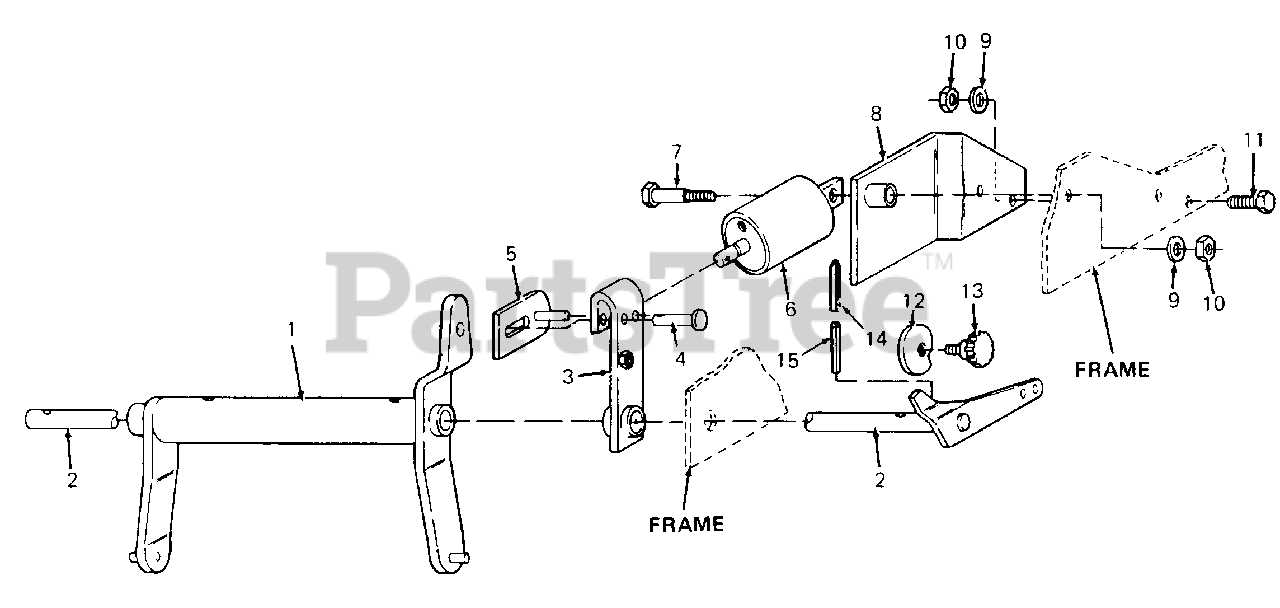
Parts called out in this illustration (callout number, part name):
1	Lift Assy, Rockshaft
2	Rockshaft Assy
3	Bracket, Lift
4	Pin, Clevis, 1/2 Dia X 2.172 Lg
5	Pin Assy, Lift
6	Cylinder, Hydraulic
7	Bolt, Shoulder
8	Bracket, Cylinder
9	Washer, Flat, .531 X 1.06 X .134 Thk
10	Nut, Hex Center Lock, 1/2-13 GR5
11	Screw, Hex Cap, 1/2-13 X 1.25 Lg GR5
14	Pointer, Lift
15	Pin, Roll, 3/16 Dia X 3.0 Lg
